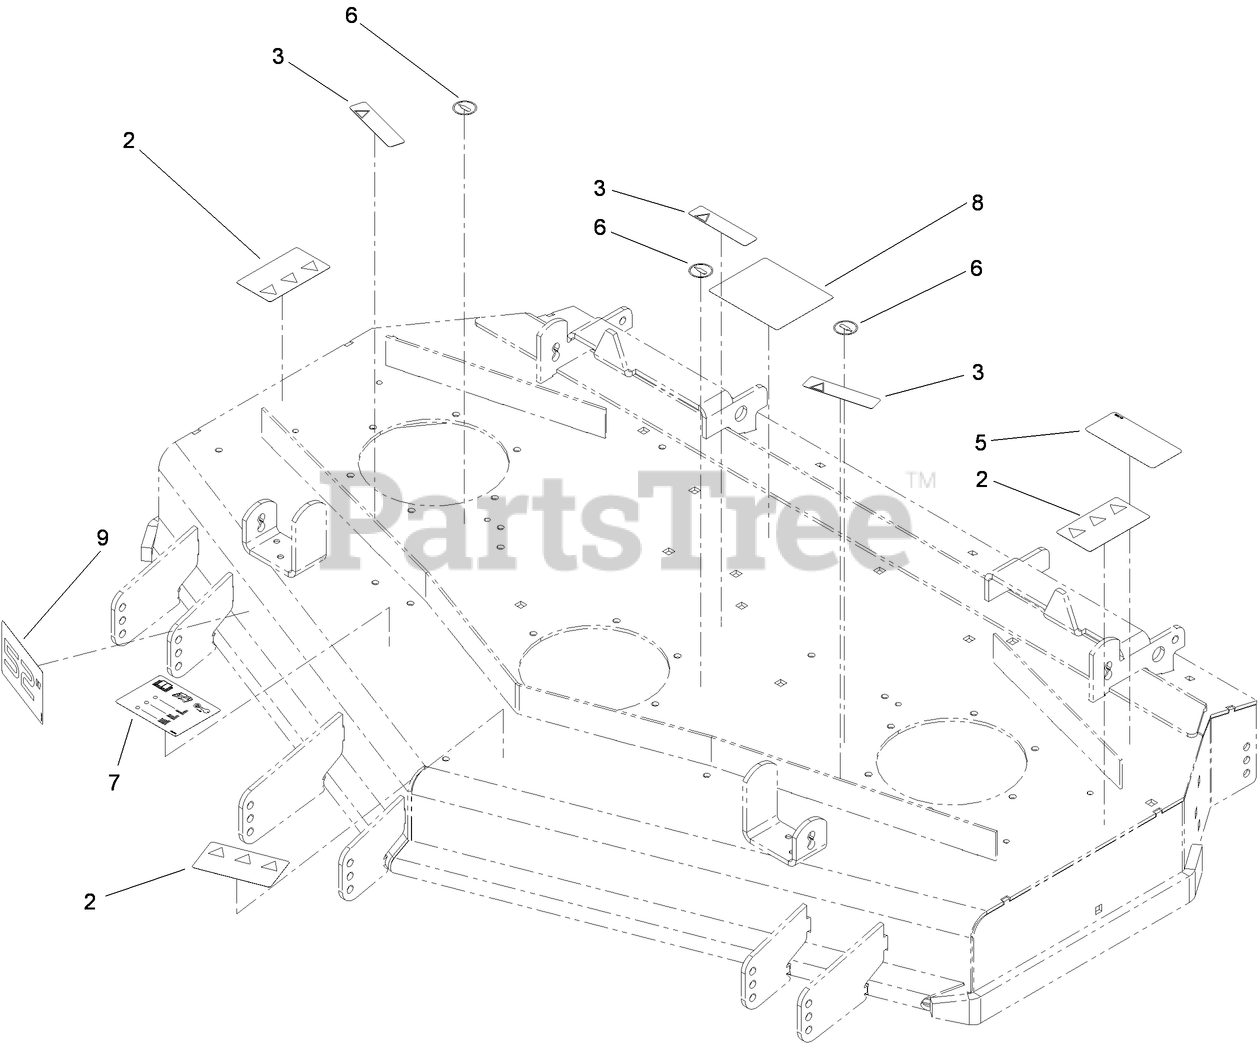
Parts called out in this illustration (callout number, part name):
2	DECAL-DANGER
3	DECAL-WARNING
5	DECAL-TORQUE, BLADE BOLT
6	DECAL-GREASE
7	DECAL-SCALP, ANTI
8	DECAL-ROUTING, BELT
